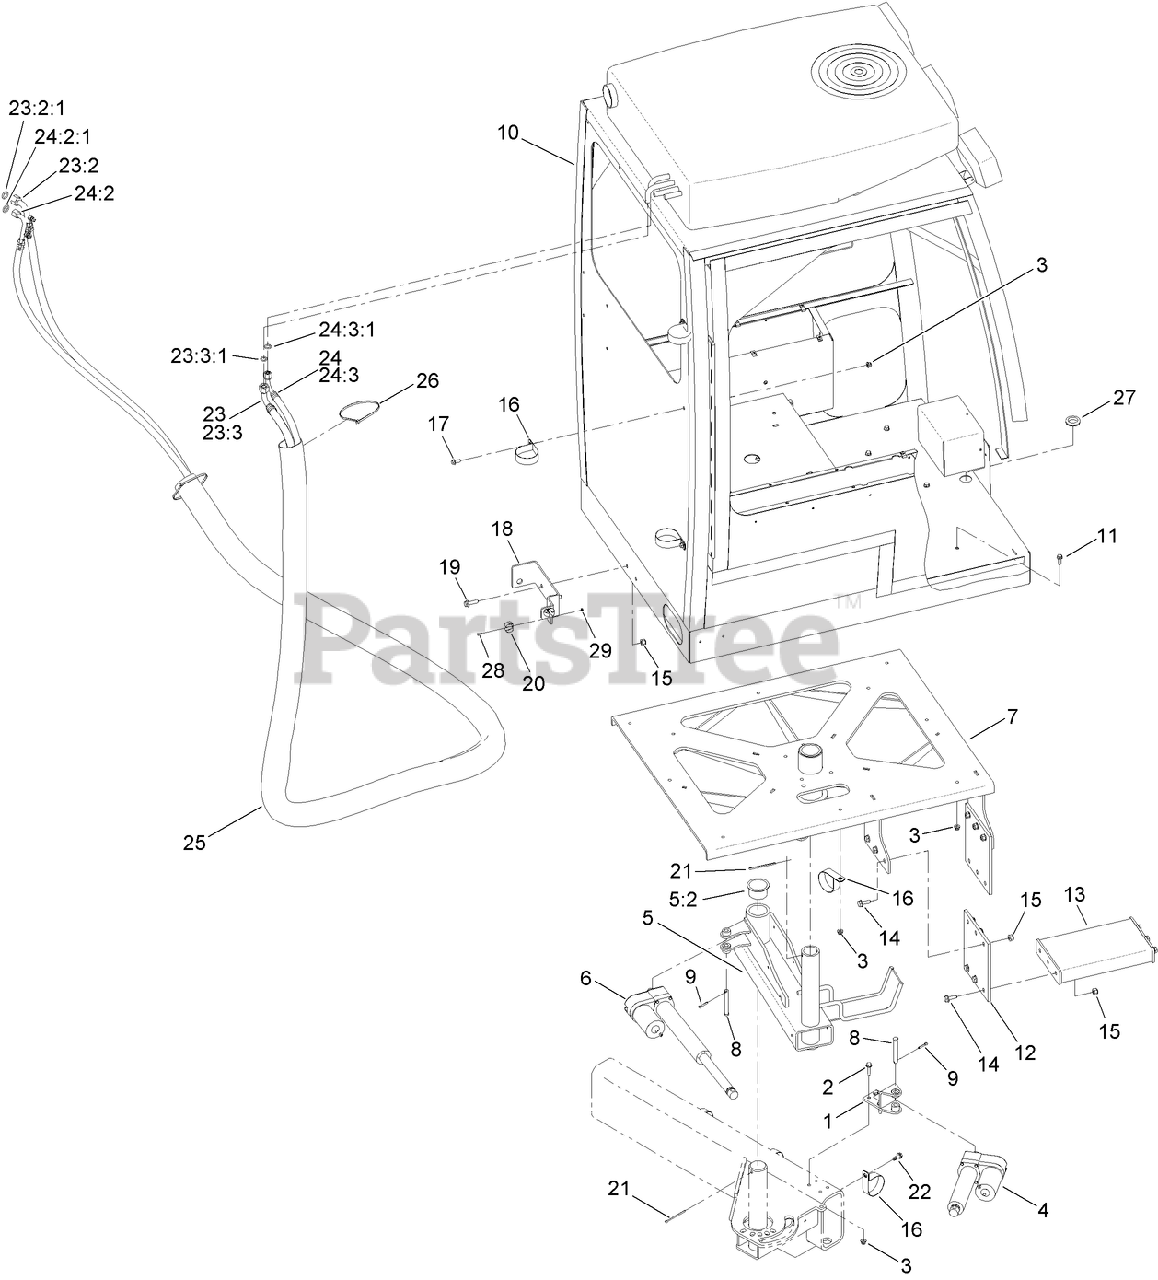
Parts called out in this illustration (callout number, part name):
1	BRACKET-CAB
2	SCREW-HHF
3	NUT-LOCK, HHF
4	CYLINDER-ELECTRIC, 4 INCH
5	CAB PIVOT ASM
5:2	BEARING-FLANGED
6	CYLINDER-ELECTRIC, 8 INCH
7	CAB MOUNT ASM
8	PIN-CLEVIS
9	PIN-COTTER
10	OPERATOR CAB ASM
11	SCREW-HHF
12	STRAP-SUPPORT, STEP
14	SCREW-HHF
15	NUT-LOCK, NI
16	CLAMP-SUPPORT
17	SCREW-HHF
18	PLATE-RETAINING, CORD
19	SCREW-HHF
20	CLIP-SPRING
21	PIN-COTTER
22	Screw-Tapping
23	HOSE ASM
23:2	FITTING-90 DEG, FEMALE
23:2:1	O-RING
23:3	FITTING-90 DEG, FEMALE
23:3:1	O-RING
24	HOSE ASM-AC
24:2	FITTING-90 DEG, FEMALE
24:2:1	O-RING
24:3	FITTING-90 DEG, FEMALE
24:3:1	O-RING
25	SLEEVE-PROTECTIVE
26	TIE-CABLE
27	GROMMET-RUBBER
28	SCREW-PRH
29	NUT-KEPS
